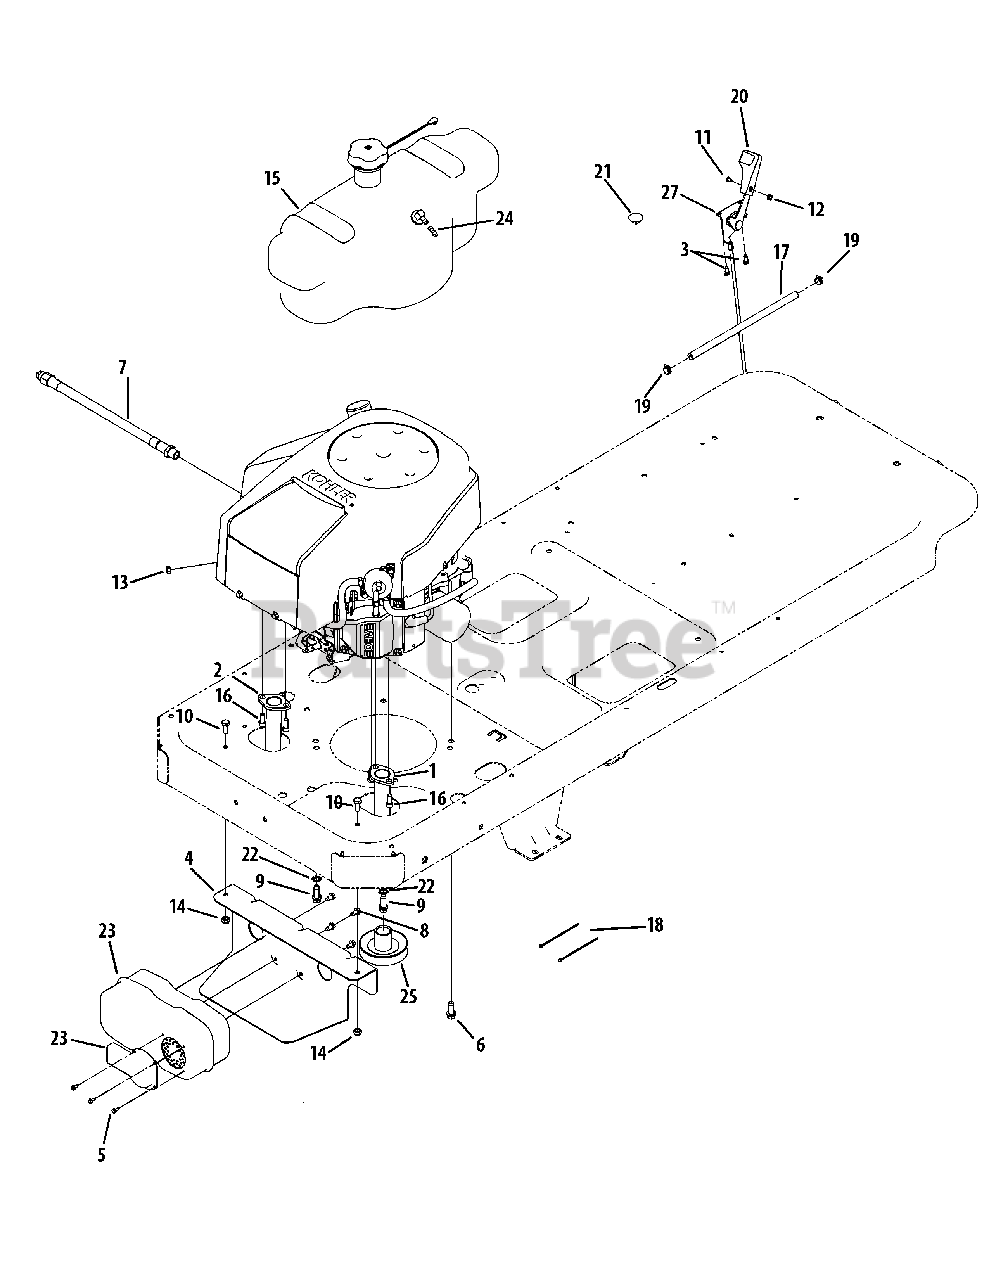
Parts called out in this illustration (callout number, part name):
1	Exhaust Pipe RH
2	Exhaust Pipe LH
3	Hex Wash. Hd. Tapp. Screw 1/4-14 x .625
4	Muffler Mtg. Bracket
5	Hex Wash HD AB S-Tapp Screw #8-.50
6	Hex Screw. #12-16 x .50
7	Oil Drain Hose
8	Hex Wash S-Tapp Screw 1/4-20 x .50
9	TT Screw 3/8-16 x 1.25
10	Hex Bolt 5/16-18 x .75" Lg. Gr. 5
11	Torx Screw, #8-32 x .375
12	Hex Nut #8-32, 0.375
13	Sems Hex Nut 1/4-20
14	Flange Locknut 5/16-18 Gr. F, Nylon
15	Fuel Tank Ass'y 2.82 gal. (w/o cap)
15	Fuel Tank Bushing
15	Rubber Grommet
15	Fuel Pick-Up Fitting
15	Fuel Cap
15	Roll over Valve
16	Soc Screw 5/16-18 x .75
17	Fuel Hose; Low Permeation, 8" Lg.
18	Cable Tie
19	Hose Clamp
20	Throttle Control Knob
21	Choke Plug
22	L-Washer 3/8" ID (Ext. Tooth)
23	Muffler
24	Fuel Line 34" Lg.
25	Engine Pulley, Electric PTO
27	Throttle/Choke Cable 41.5" Lg.
28	Muffler Deflector
